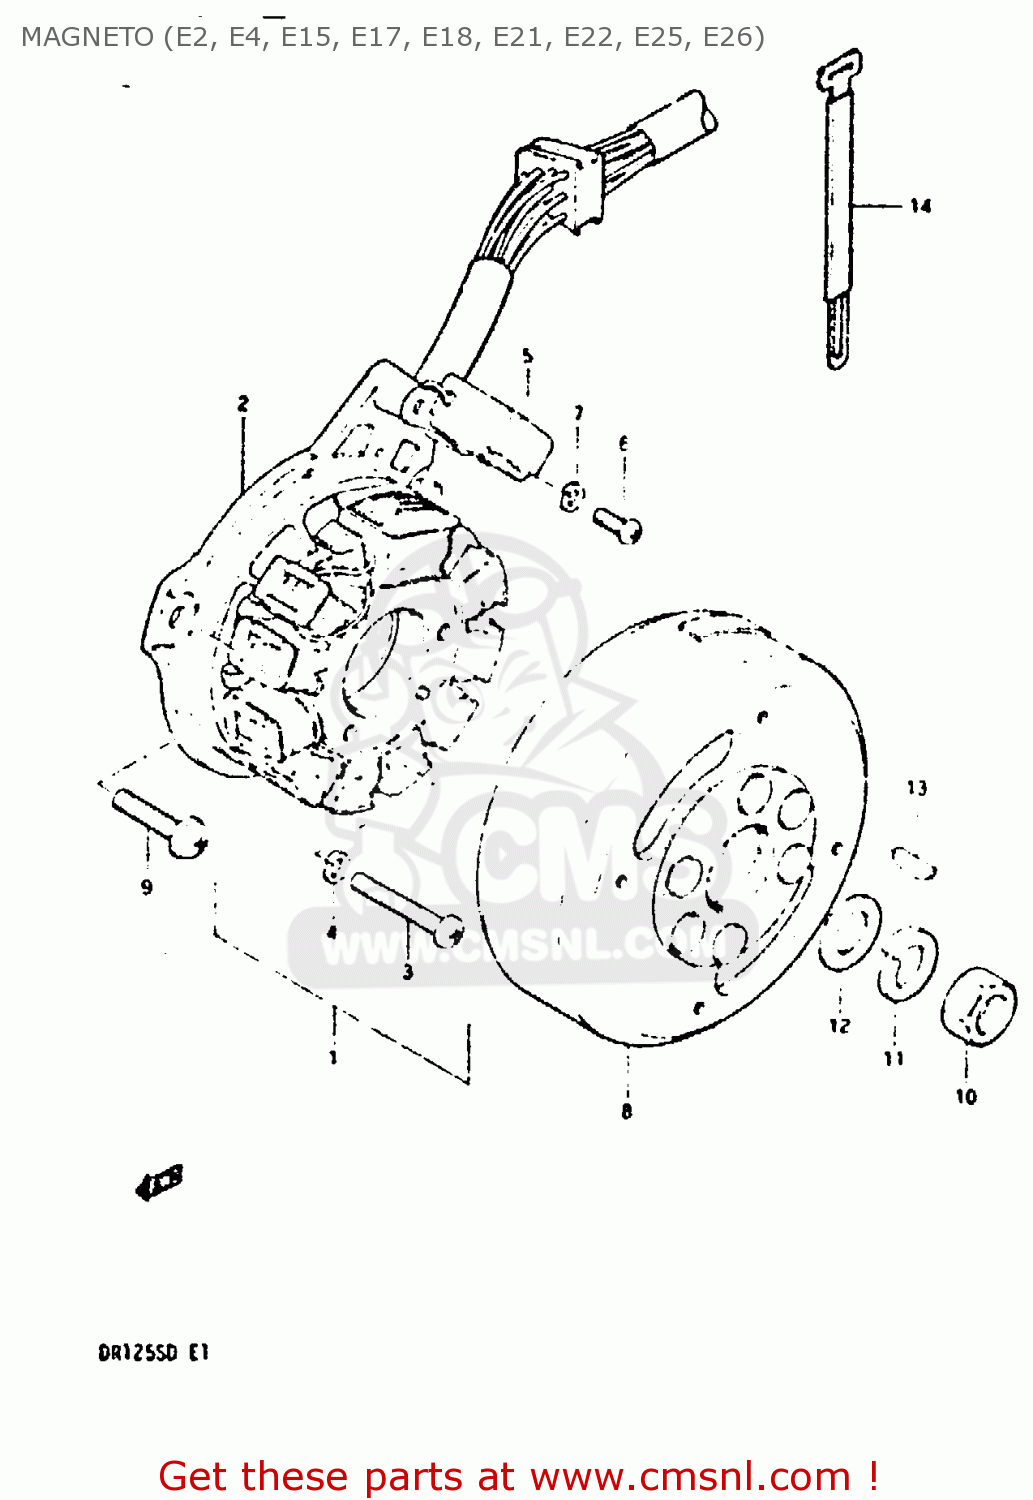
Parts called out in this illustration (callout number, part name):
1	STARTER ASSY
2	COIL,STARTER
3	SCREW
4	LOCK WASHER
5	COIL
6	SCREW
7	LOCK WASHER
8	ROTOR ASSY
9	SCREW(5X14)
10	NUT (10MM)
11	LOCK WASHER
12	WASHER
13	KEY
14	CLAMP L:110
